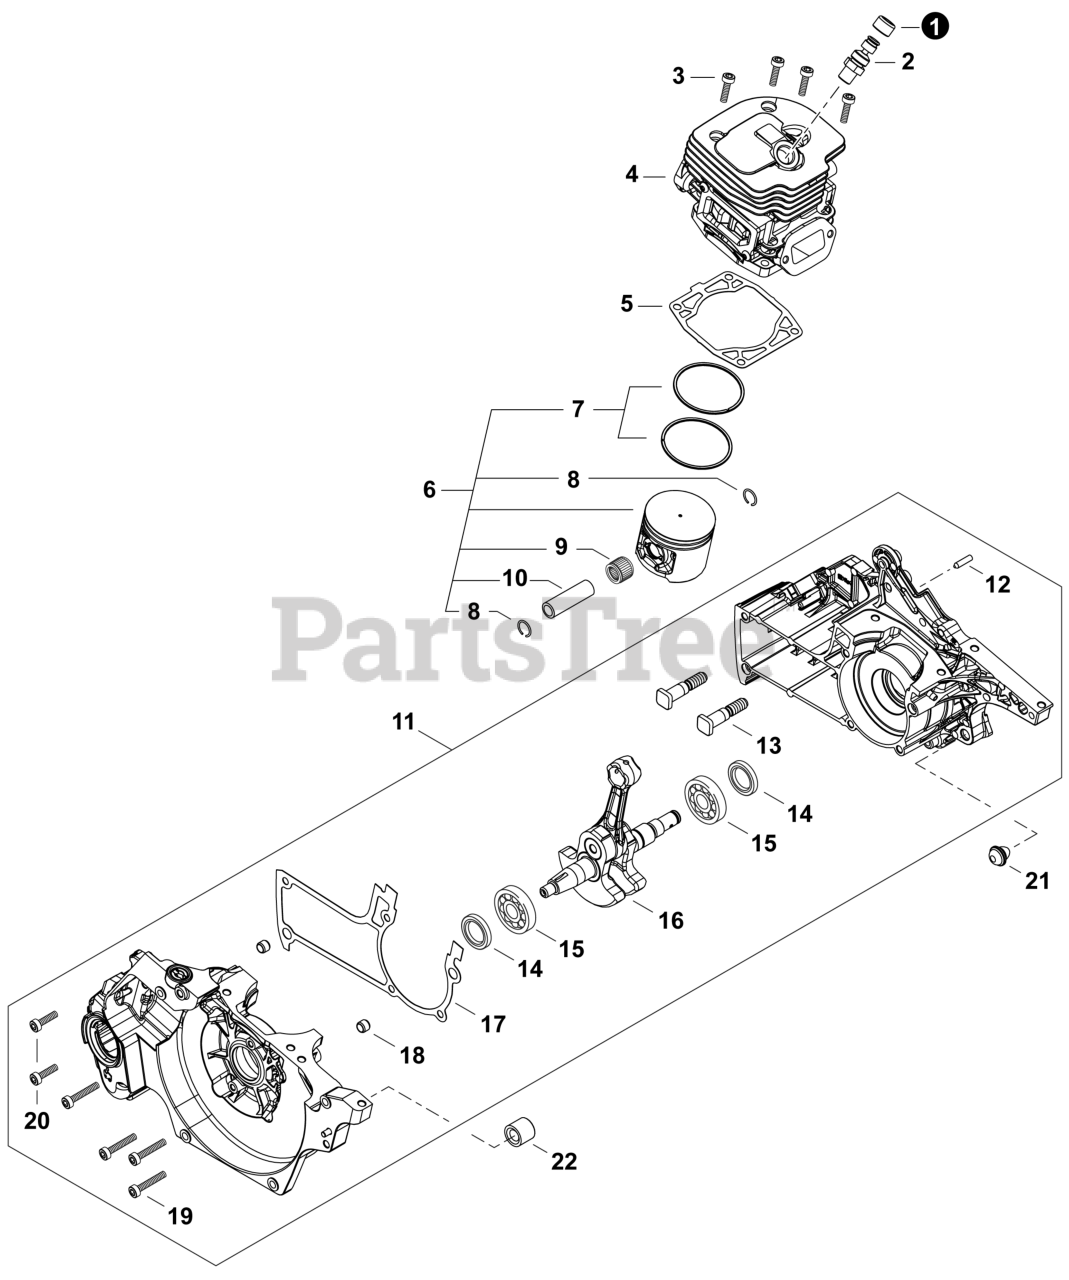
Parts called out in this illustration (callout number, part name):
1	COVER, DUST
2	DECOMPRESSION ASSY
3	BOLT, TORX 5x25
4	CYLINDER ASSY
5	GASKET, CYLINDER
6	PISTON KIT
7	RING, PISTON
8	RING, SNAP
9	BEARING, NEEDLE 12
10	PIN, PISTON 12
11	CRANKCASE KIT
12	VENT ASSY
13	BOLT, STUD 8
14	SEAL, OIL 15
15	BEARING, BALL 6202
16	CRANKSHAFT ASSY
17	GASKET, CRANKCASE
18	COLLAR 6
19	BOLT, TORX 5x35
20	BOLT, TORX 5x25
21	CUSHION
22	CUSHION
